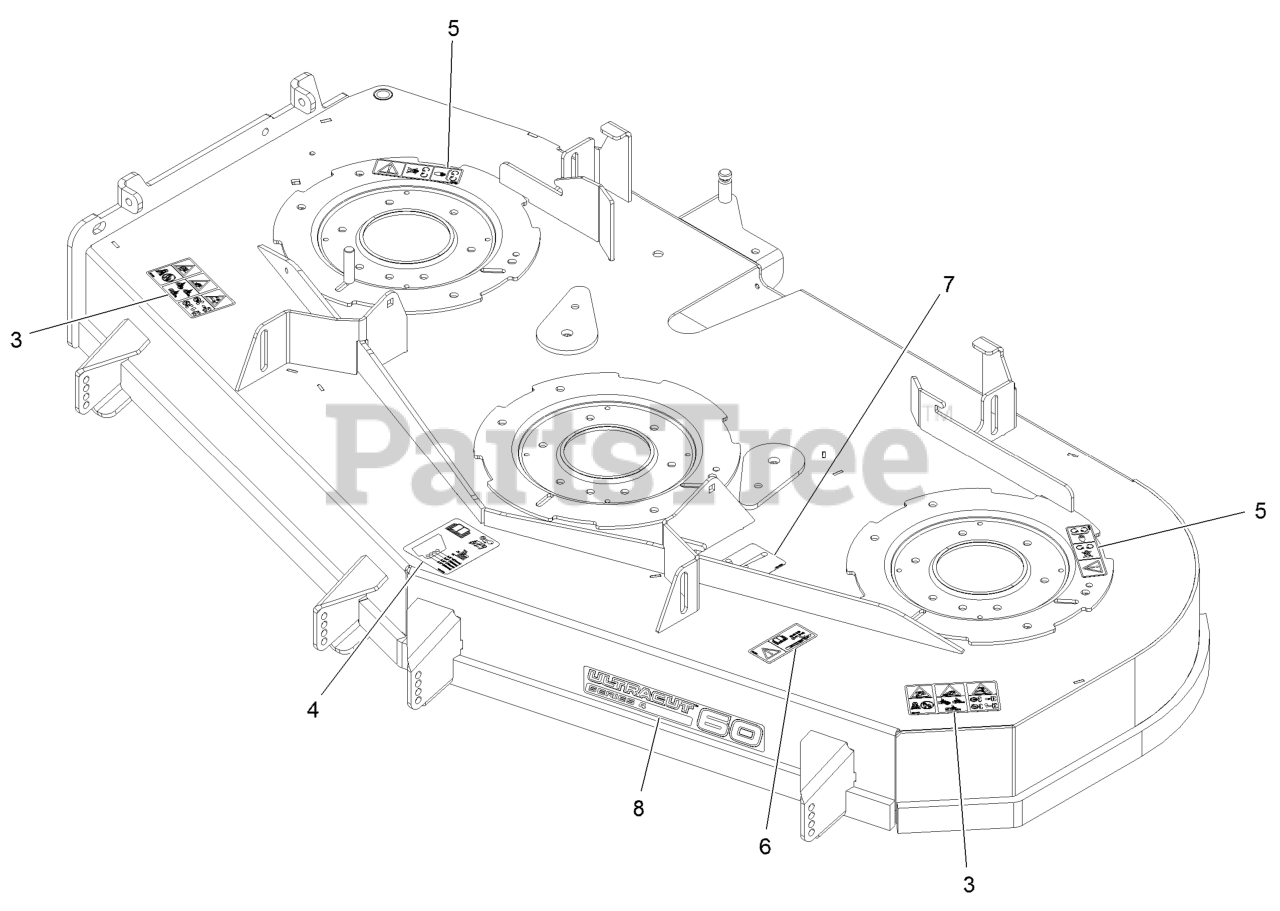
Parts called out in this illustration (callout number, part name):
3	DECAL-DANGER THROWN OBJECTS
4	DECAL-ROLLER, ANTI-SCALP
5	DECAL-COVER, MISSING
6	DECAL-BOLT TORQUE
7	DECAL-ROUTING, BELT
8	DECAL, 604
